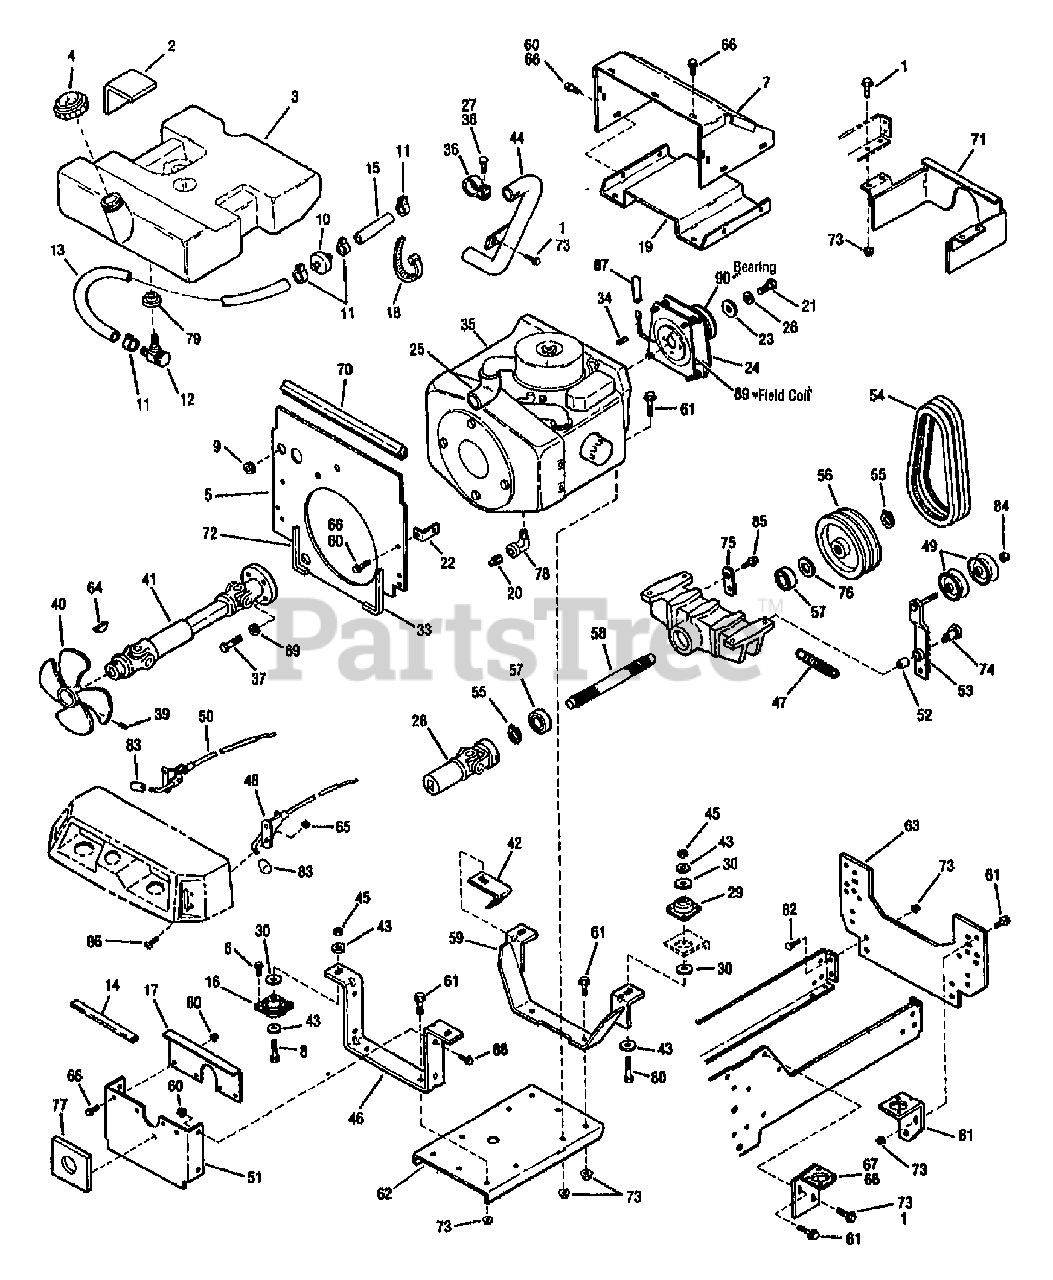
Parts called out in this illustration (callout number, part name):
2	PAD-FUEL TANK
3	ASSM-FUEL TANK
4	CAP-FUEL
5	SHIELD-HEAT
7	ASSM-HEAT SHIELD
8	SCR-HH 3/8-16X2.25 G5 ZP
9	BUSHING
10	FILTER-FUEL
11	CLAMP-HOSE
12	VALVE-SHUT OFF
13	FUEL LINE
14	GASKET-HEAT SHIELD
15	LINE-FUEL
17	SHIELD-GRASS UPPER
18	TIE-CABLE NYLON BLACK
19	SHIELD-HEAT
20	PLUG-PIPE
21	SCR-HH 7/16-20X1.25 G5ZP
22	BRKT-HEAT SHIELD
23	WASHER-1.7X.453X.25
24	CLUTCH {13062}
24	ELEC-CLUTCH/BRAKE {13060}
25	HOSE-AIR CLEANER
26	WASHER-LK .438 ZP
27	NUT-H/LK 5/16-18
28	JOINT-UNIVERSAL
28	KIT-CROSS REPAIR
29	MOUNT
30	WASHER
33	SEAL-RH
35	KOHLER ENGINE 20HP {KT200S 49540}{13062} {M20QS 49565}
35	KOHLER ENGINE 18HP {M18QS 24999}{13060}
36	CLAMP
37	SCR-HH 3/8-16X1.0 G5 ZP
38	SCR-CARR 5/16-18X1.25 G2ZP
39	SCR-SQ HD SET 5/16X3/4
40	FAN
41	SHAFT-DRIVE
42	BRKT-EXHAUST PIPE
43	WASHER-FLAT 1.25X.406X.179
44	PIPE-EXHAUST
45	NUT-LOCK 3/8-16
46	SUPPORT-REAR MOUNT
47	SPRING
48	THROTTLE-CONTROL
49	PULLEY-IDLER
50	CHOKE-CONTROL
51	SHIELD-GRASS LOWER
52	BUSHING
53	ARM-IDLER
54	BELT SET
55	RING-HEAVY EXT HD 1.0 ID
56	SHEAVE-PTO
57	BEARING-BALL
58	SHAFT-PTO
59	SUPPORT-FRONT MOUNT
60	NUT-HF/LK 1/4-20 ZP
61	SCR-HFLK 3/8-16X1.00 ZP
62	MOUNT-ENGINE
63	PLATE-FRONT
64	KEY-WOODRUFF
65	NUT W/LKWASHER 10-24 ZP
66	SCR-HFLK 1/4-20X.50 ZP
67	ASSM-HANGER RH
68	ASSM-HANGER LH
69	WASHER-LK .375 @ DEPL
71	GUARD-PTO
72	SEAL-LH
73	NUT-HFLK 3/8-16 ZP
75	ANCHOR-SPRING
76	WASHER-THRUST
78	ELBOW-45 DEGREES
79	BUSHING-RUBBER
80	SCR-HHC 3/8-16X3.25
81	SUPPORT-ENGINE
82	SCR-CARR 3/8-16X.75 G5 ZP
83	KNOB
84	NUT-HEX/JAM 3/8-16 ZP
85	SCR-HFLK 5/16-18X.75 ZP
90	BEARING
